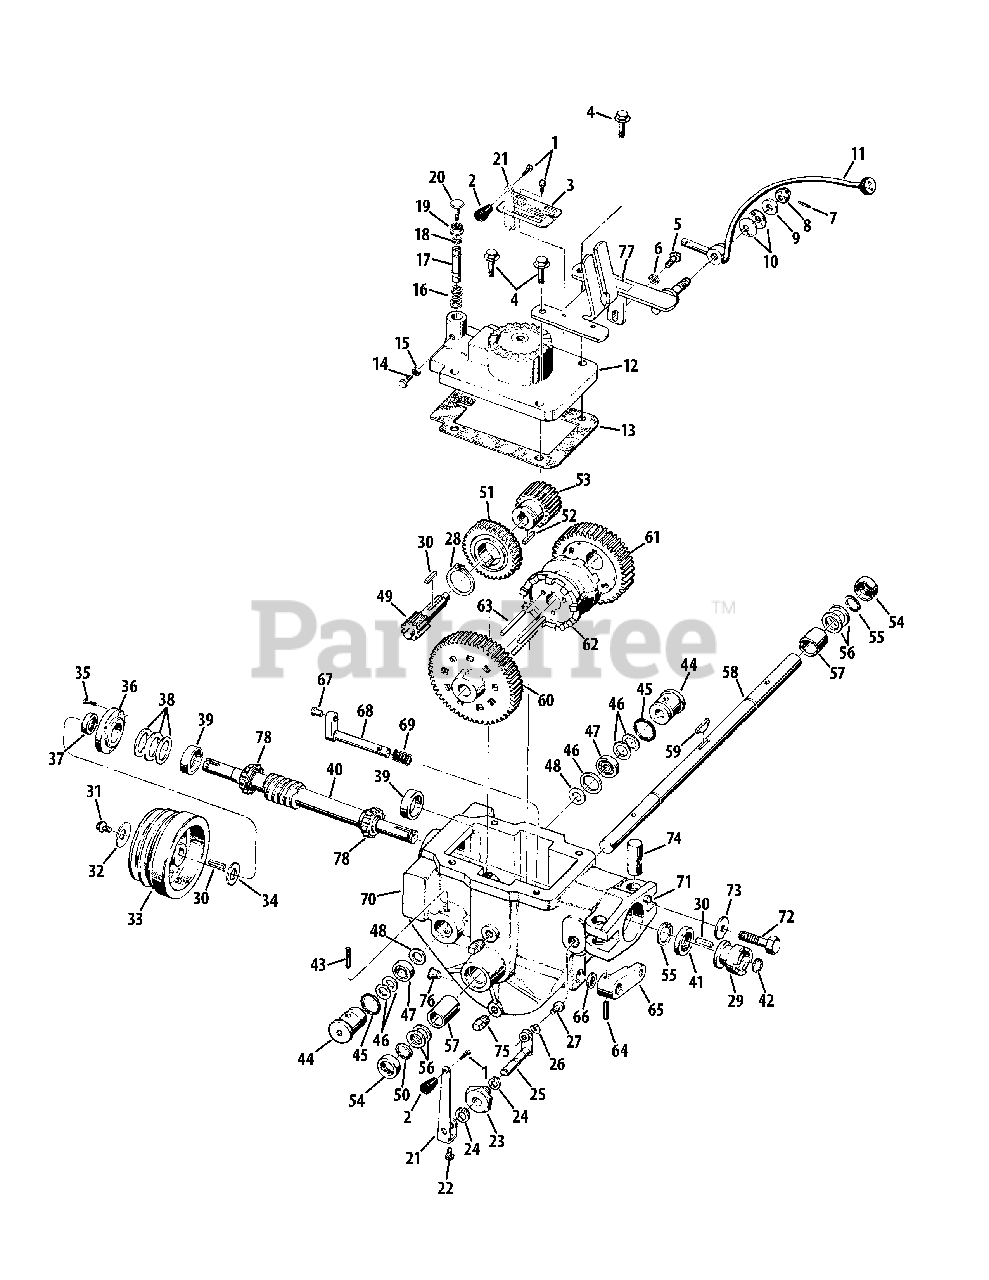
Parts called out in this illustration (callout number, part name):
1	Hex Head Screw, #10-32 x 3/8"
4	Hex Flange Bolt, 3/8"-16 x 1-1/2"
5	Hex Flange Bolt, 5/16"-18 x 3/4"
6	Flat Washer, 5/16"
7	Spring Pin, 1/8"
8	Hex Nut, 1/2"-20
8	Flat Washer, .510 x 1.0 x .125
9	Shoulder Washer, 1.25 x .50 x .25
10	Disc Spring Washer, 1.97 x 1.0 x .118
11	Wheel Speed Shift Lever
12	Power Unit Transmission Cover
13	Transmission Cover Gasket
14	Hex Head Screw, 5/16"-18 x 1"
15	Hex Nut, 5/16"-18
16	Plunger Spring
18	Clip Ring
19	Flange Lock Nut, 3/8"-16
20	Screw, 3/8"-16 x 1-1/2"
21	Tines/PTO Clutch Lever
22	Hex Head Screw, 1/4"-20 x 1/2"
23	Tines/PTO Clutch Bushing
24	External Retaining Ring
25	Tines/PTO Clutch Shaft
26	Hi-Collar Lockwasher, 1/4"
27	Socket Head Screw, 1/4"-20 x 3/8"
28	External Retaining Ring
29	Dog Clutch
30	Key, 3/16" x 1"
31	Hex Head Screw, 5/16"-24 x 3/4"
32	Spring Washer, .827 x .331 x .098
33	Transmission Drive Pulley
34	Flat Washer, 1.25 x .687 x .075
35	Flange Nut, 1/4"-20 x .75
36	Front Bearing Cap
38	Flat Washer, 1.175 x 1.5 x .062
38	Flat Washer, 1.175 x 1.5 x .005
38	Flat Washer, 1.175 x 1.5 x .03
38	Flat Washer, 1.175 x 1.5 x .01
39	Cup Bearing
40	Main Drive Shaft
42	Retaining Ring
43	Roll Pin (Spirol), 1/4" x 2
44	Pinion Bearing
46	Flat Washer, 1.234 x 1.015 x .062
46	Flat Washer, 1.234 x 1.015 x .033
46	Flat Washer, 1.234 x 1.015 x .01
47	Ball Bearing
48	Washer
49	Pinion Stem
50	External Retaining Ring, 1.387 ID
51	Worm Gear
52	Key, 3/16" x 5/8"
53	Fast Speed Pinion Gear
55	External Retaining Ring
56	Flat Washer, 1.375 x 1.015 x .005
56	Flat Washer, 1.375 x 1.015 x .01
56	Flat Washer, 1.375 x 1.015 x .015
56	Flat Washer, 1.375 x 1.015 x .03
56	Flat Washer, 1.375 x 1.015 x .062
57	Bushing, 1.25 x 1.005 x 1.5
58	Wheel Shaft
59	Hi-Pro Key, .250 x 1.8125
60	Slow Speed Gear
61	Faste Gear Speed
62	Dog Clutch
63	Clutch Guide Pin, 1/4"
64	Spring Pin, 3/16" x 1-1/4"
65	Wheel Speed Shifting Lever
67	Wheel Speed Shifting Pin
68	Wheel Speed Shifting Shaft
70	Transmission Housing
71	Alignment Pin
72	Hex Screw, 1/2"-13 x 2"
73	Disc Spring Washer
75	Pipe Plug, 1/4"
76	Plug-Red Plastic
77	Clutch Bracket
78	Cone Bearing
